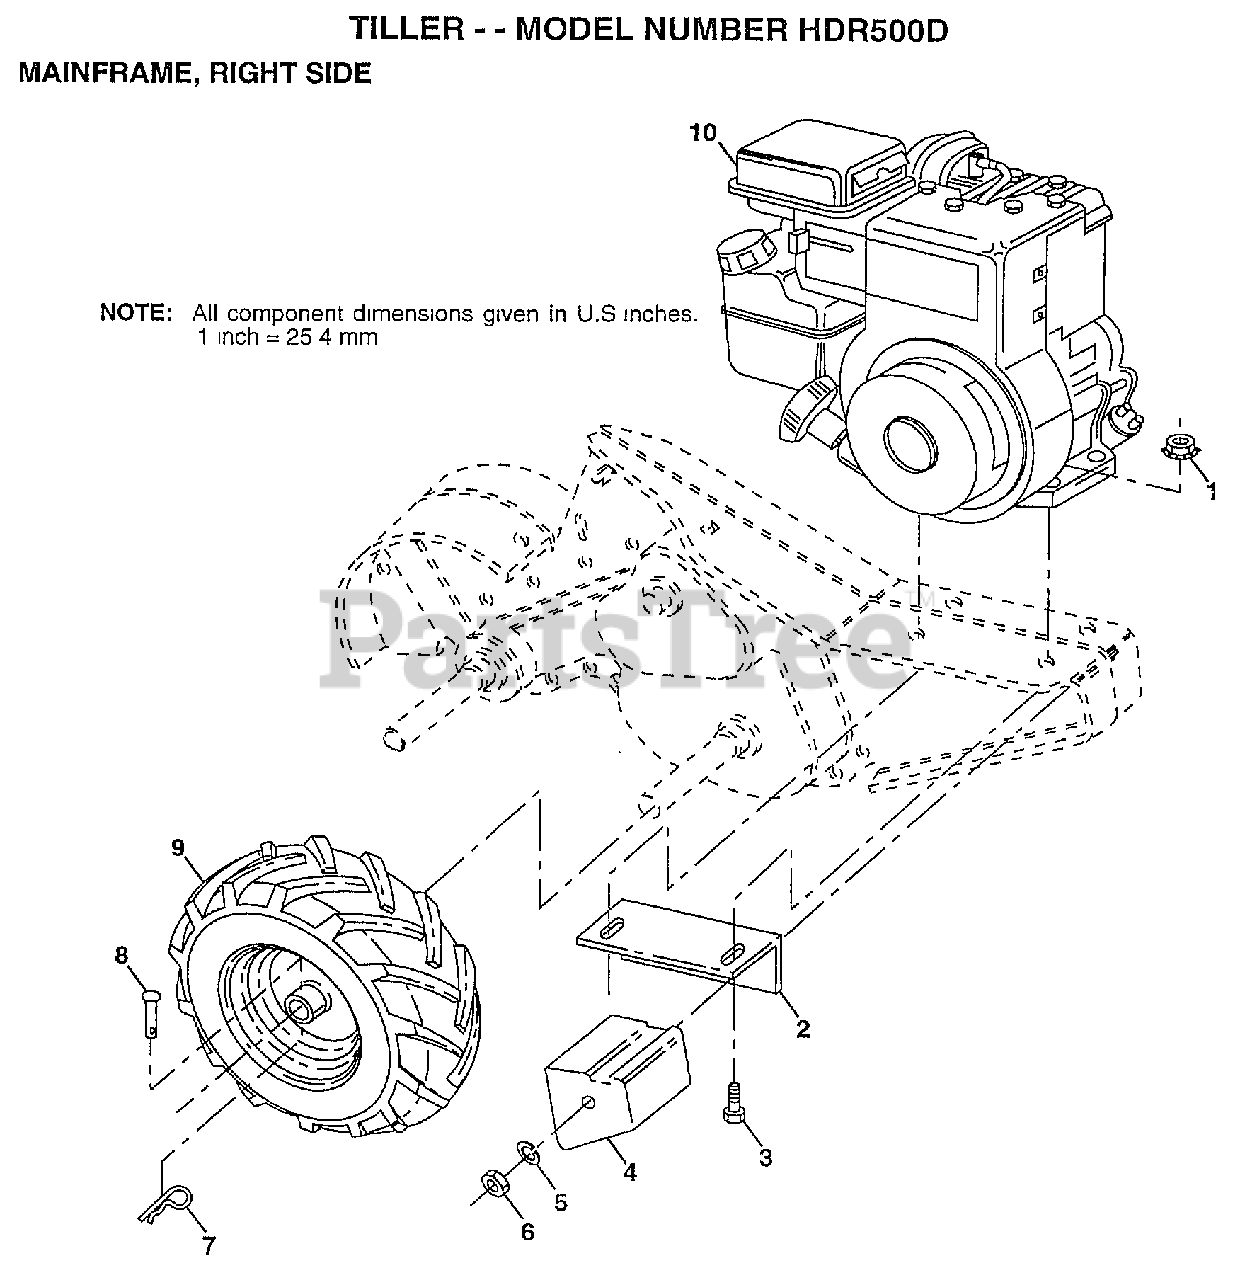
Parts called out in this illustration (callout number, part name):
2	BRACKET RH CRT
3	BOLT.HEX.5/16-1.5
4	COUNTERWEIGHT CRT
5	LOCKWASHER
6	NUT.HEX.3/8-16UNC
7	RETAINER M
8	RIVET.DRILL.1.75
9	TIRE.CHV.13X5.0-6
